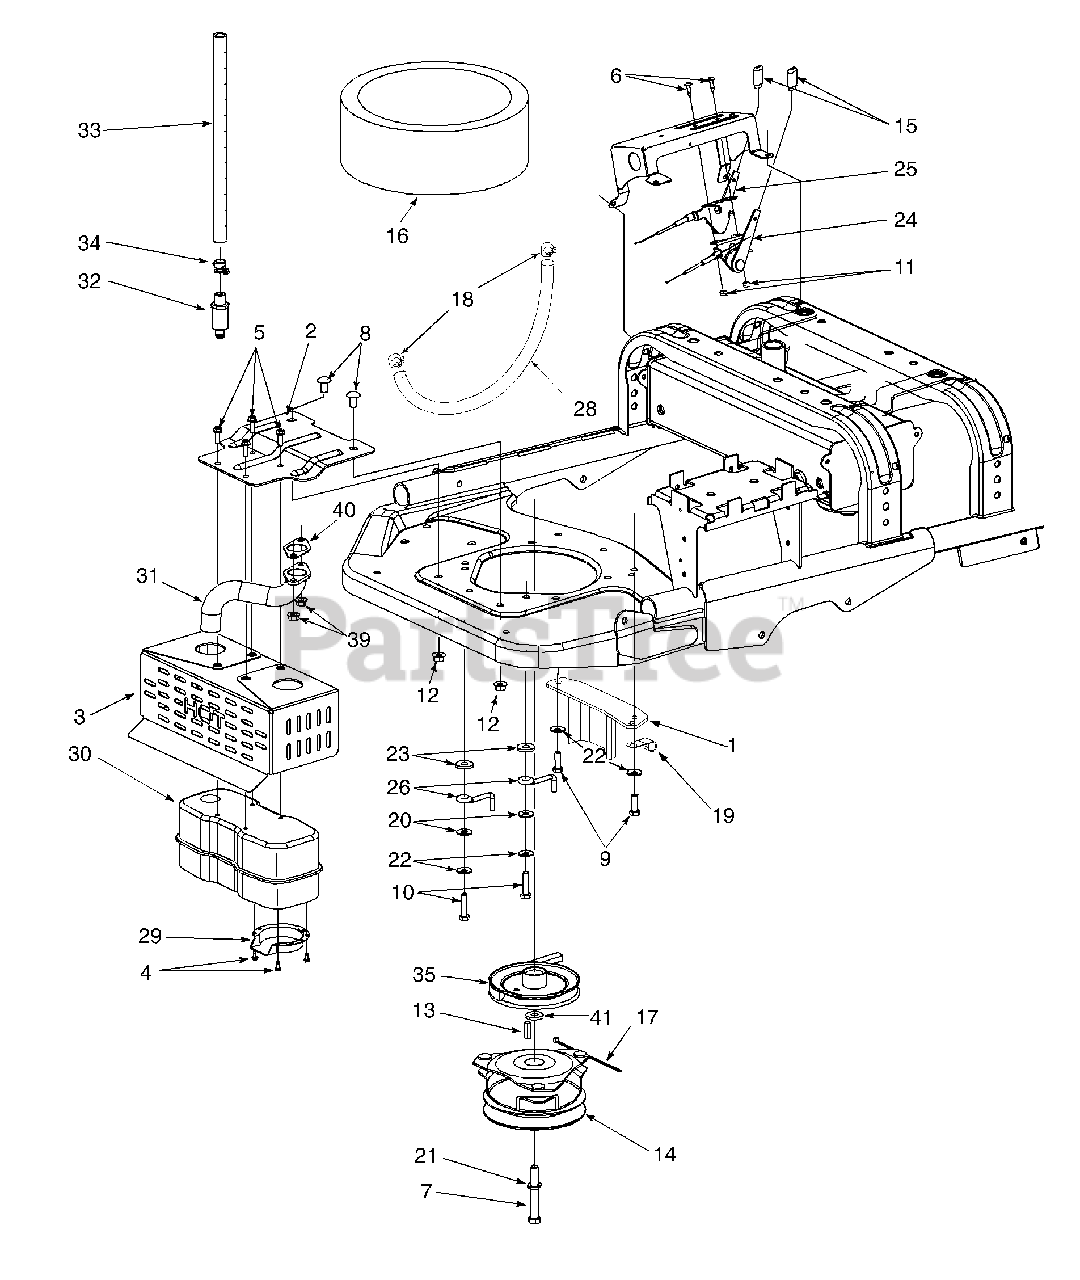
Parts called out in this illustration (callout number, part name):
5	Screw, Hex Wash Hd Tapp 1/4-20 x .75
6	Screw, Phil. Pan Hd,10-24 x .75
7	Screw, Hex Cap 7/16-20 x 3.25 GR5
8	Bolt, Carriage, 3/8-16 x .75
9	Screw, Hex Cap, M8-1.25 x 25 Gr 8.8
10	Screw, Hex Cap, M8-1.25 x 35 Gr 8.8
11	Nut, Hex, #10-24
12	Nut, Hex Flange Lock, 3/8-16
13	Key, Square, 1/4 x 1.0
14	Clutch Assembly, PTO
16	Seal Ring, Foam Gasket
17	Cable Tie
18	Clamp, Hose
19	Clip, Cable
20	Washer, Flat 5/16
21	Washer, Lock, 7/16
22	Washer, Bell, .340 x .872 x .06
23	Washer, Flat, .385 x 1.0 x .135
24	Cable, Choke Control
25	Cable, Throttle Control
26	Rod, Rear Belt Retainer
28	Fuel Line Hose 9" Length
29	Deflector, Muffler
30	Muffler, Single Inlet
31	Pipe, Exhaust
32	Drain, Oil
33	Extension Hose, Oil Drain 13" Lg
34	Cap, Oil Drain
35	Pulley, Transmission Drive
39	Nut, Hex Flange, M8 x 1.25
40	Gasket, Exhaust Manifold
41	Washer, Flat
